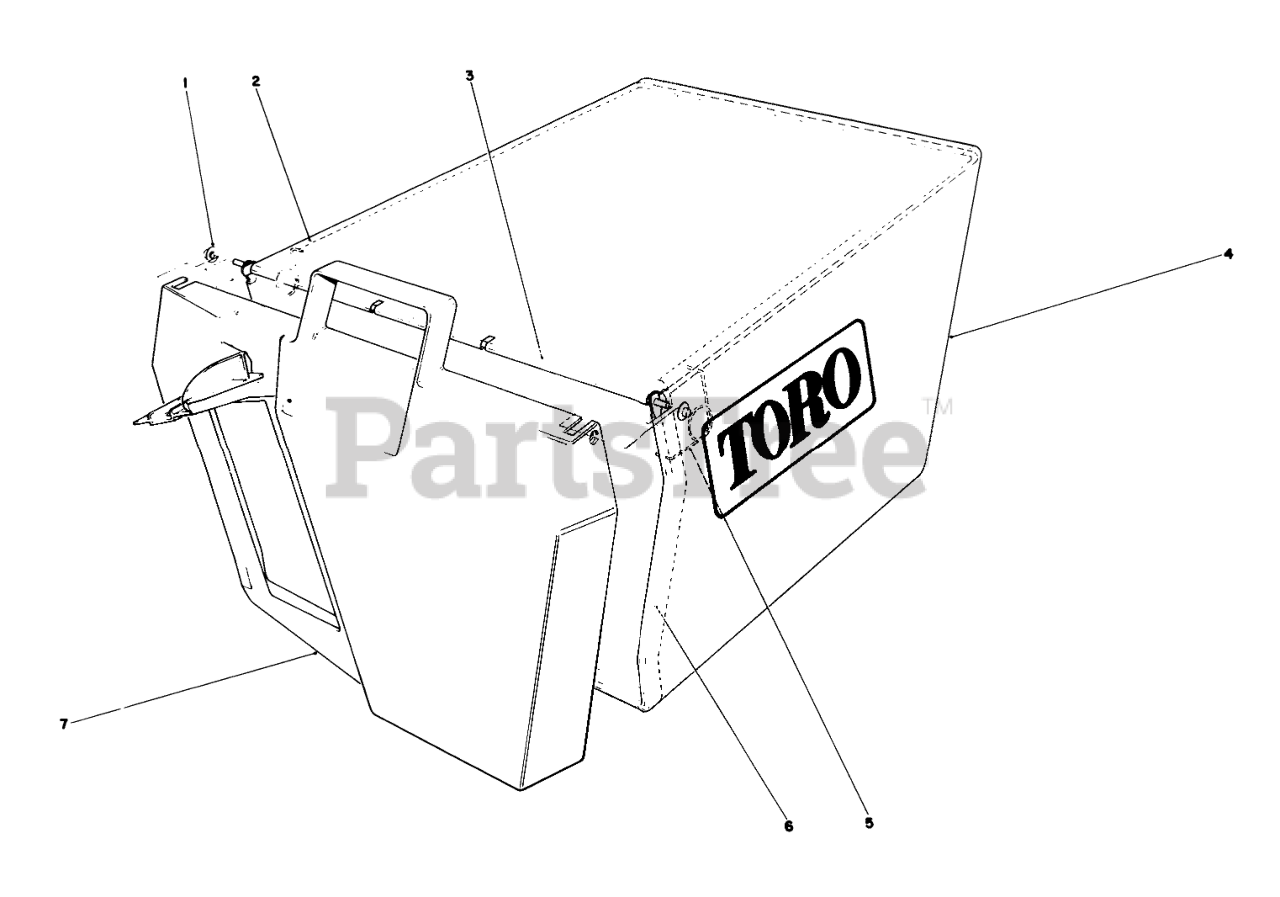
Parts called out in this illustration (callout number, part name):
1	NUT-PUSH
2	FRAME-BAG, UPPER
3	HINGE-DOOR, BAG
4	Bag
5	SPRING
6	BAG FRAME
7	Door Grass Bag
